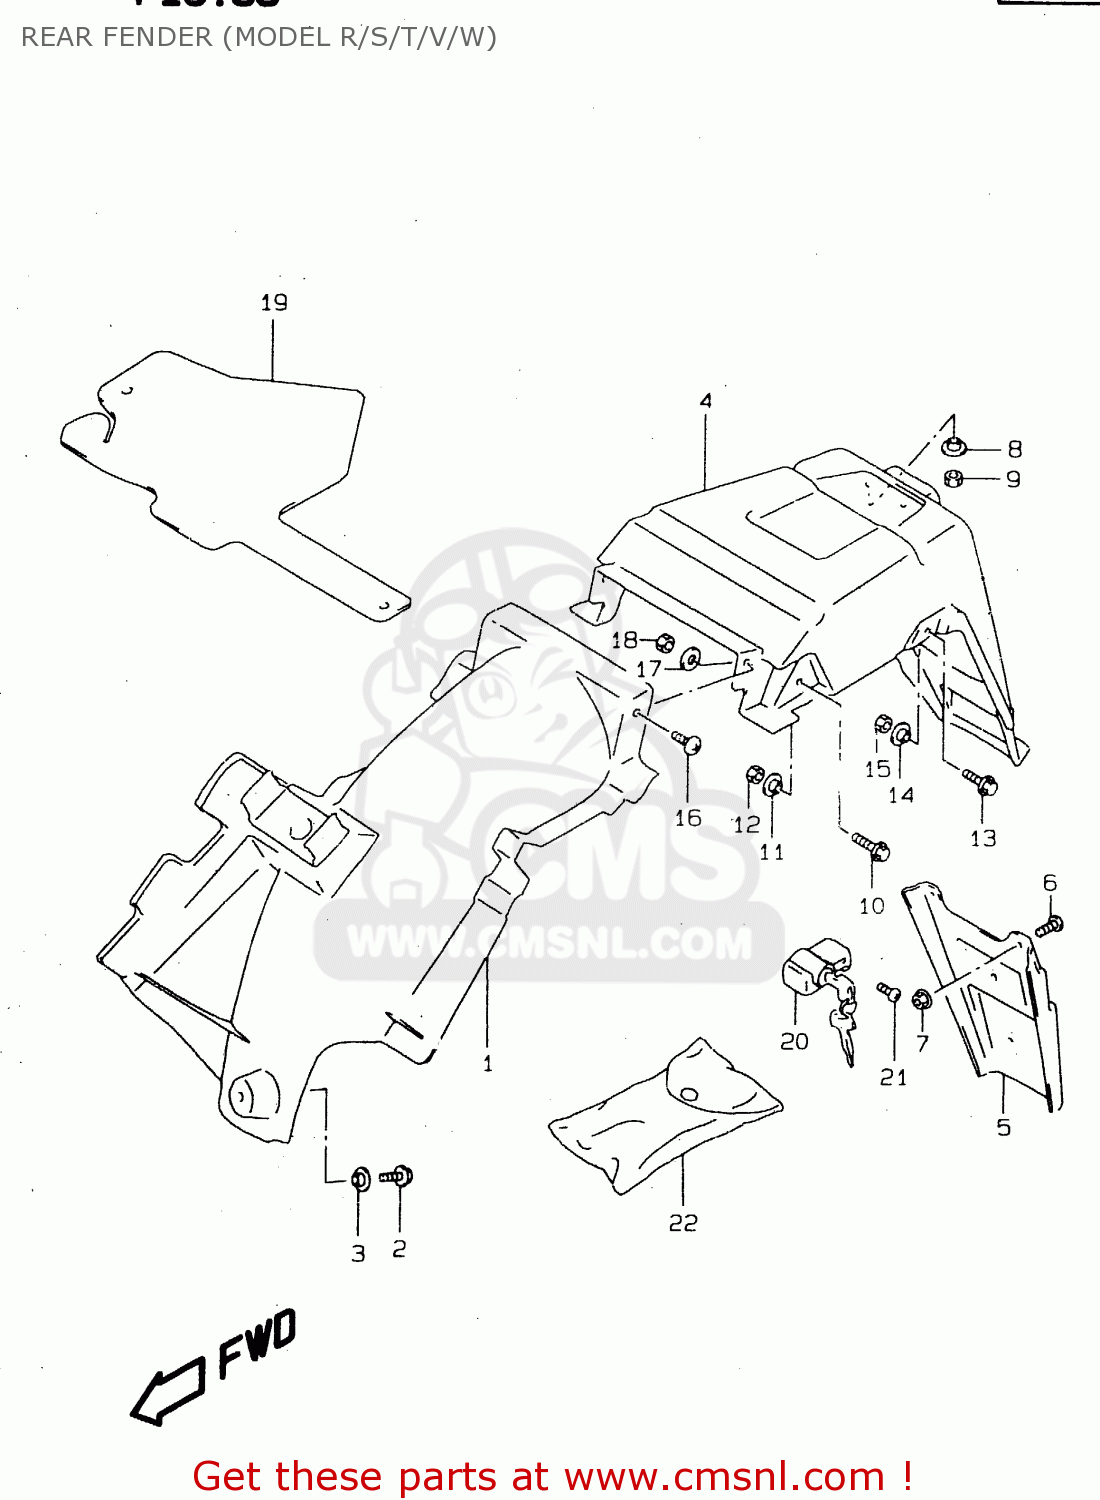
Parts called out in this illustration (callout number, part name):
1	BODY COMP,REAR FENDER
2	BOLT
3	WASHER
4	BODY,RR FENDER RR
5	EXTENSION,RR FENDER
6	SCREW
7	NUT
8	WASHER
9	NUT
10	BOLT
11	WASHER
12	NUT
13	BOLT
14	WASHER
15	NUT
16	SCREW
17	WASHER(6.5X18X1.6)
18	NUT
19	MUDFLAP,RR FENDER FR
20	LOCK SET,HELMET
21	SCREW(6X14)
22	TOOL ASSY
